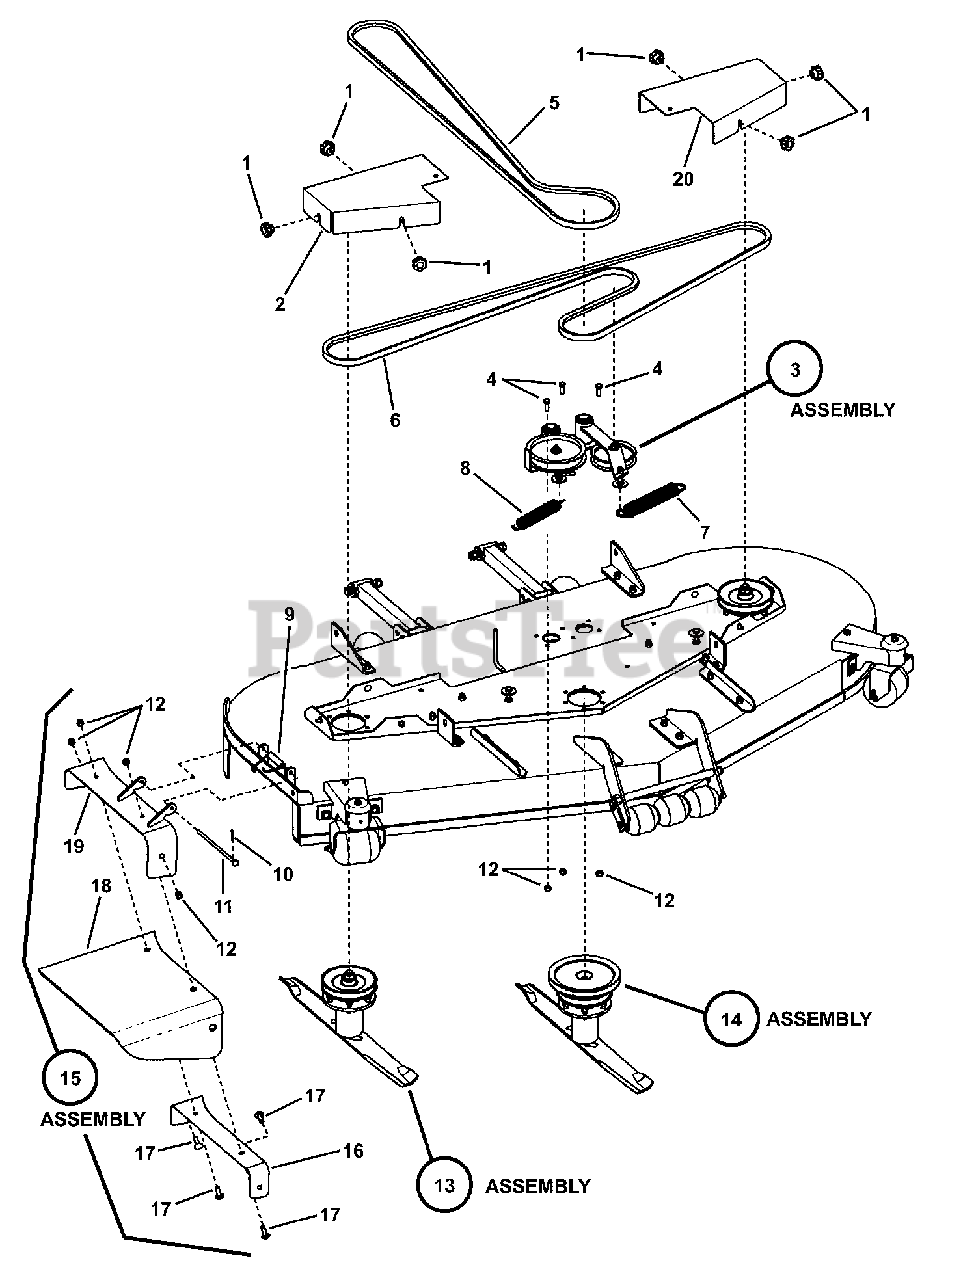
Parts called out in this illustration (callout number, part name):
1	KNOB, Fluted, 5/16-18 x 5/8"
2	GUARD, Pulley, RH
3	ASSEMBLY, Idler (see breakdown on Idler Assy page)
4	BOLT, 3/8-16 X 1" GD5 CZ
5	* BELT, HB Section, (engine to deck)
6	* V-BELT, Secondary, HB Section
7	SPRING, Extension, Lift Assist
8	SPRING, Idler Primary (1.25" O.D. x 10" long)
9	SPRING, Chute
10	COTTER PIN, 3/32 X 1"
11	PIN, Chute Hinge
12	NUT, 3/8-16 HEX NYLON LOCK
13	ASSEMBLY, Spindle (ref. Deck Spindle Assy page)
14	ASSEMBLY, Center Spindle (ref. Deck Spindle Assy page)
15	ASSEMBLY, 73" Discharge Chute
16	DEFLECTOR, Bottom, 73" Deck
17	BOLT, 3/8-16 x 1-1/4" Square Neck Carriage, GR 5
18	CHUTE, Rubber, 73"
19	WELDMENT, Discharge Chute Top, 73"
20	GUARD, Pulley, LH
